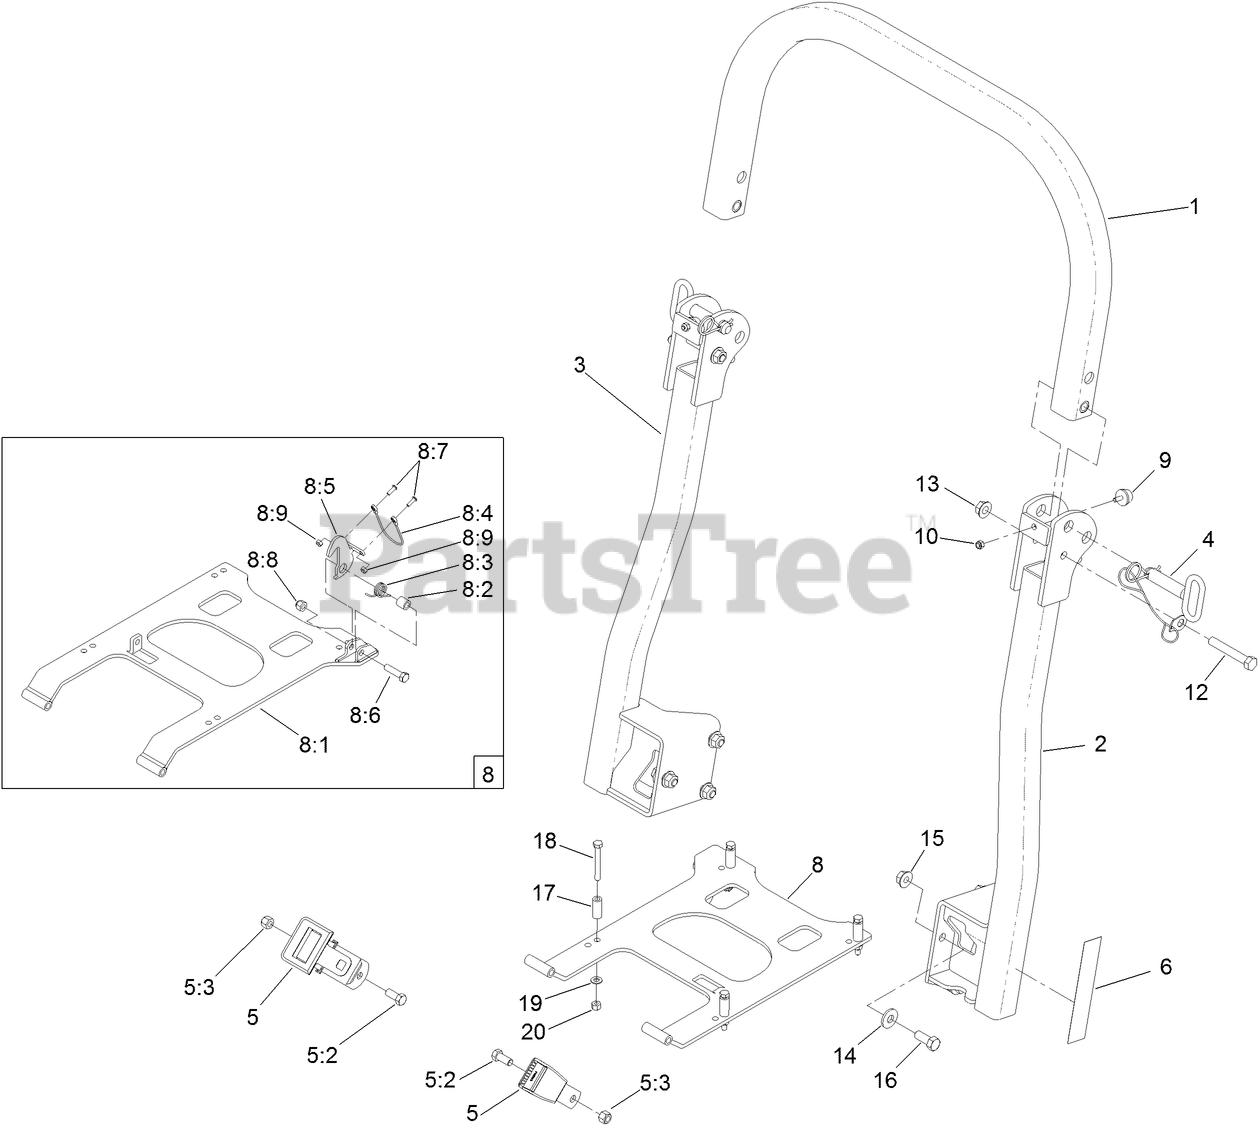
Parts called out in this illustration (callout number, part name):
1	TUBE-UPPER ROPS
2	TUBE-SUPPORT
3	TUBE-SUPPORT
4	PIN-FOLD, ROPS
5	SEATBELT KIT
5:2	SCREW-HH
5:3	NUT-LOCK
6	DECAL-WARNING
8	SEAT FRAME ASM
8:1	MOUNT-SEAT, ROPS
8:2	SPACER-KNOB, SEAT
8:3	SPRING-TORSION
8:4	CABLE GRIP ASM
8:6	SCREW-HH
8:7	SCREW-HSBH
8:8	NUT-LOCK, NI
8:9	NUT-LOCK, NI
9	BUMPER-RUBBER
10	NUT-LOCK, NI
12	SCREW-HH
13	NUT-HF
14	WASHER-SPRING
15	NUT-HHF
16	SCREW-HH
17	SPACER
18	SCREW-HH
19	WASHER-PLAIN
20	NUT-LOCK, NI
